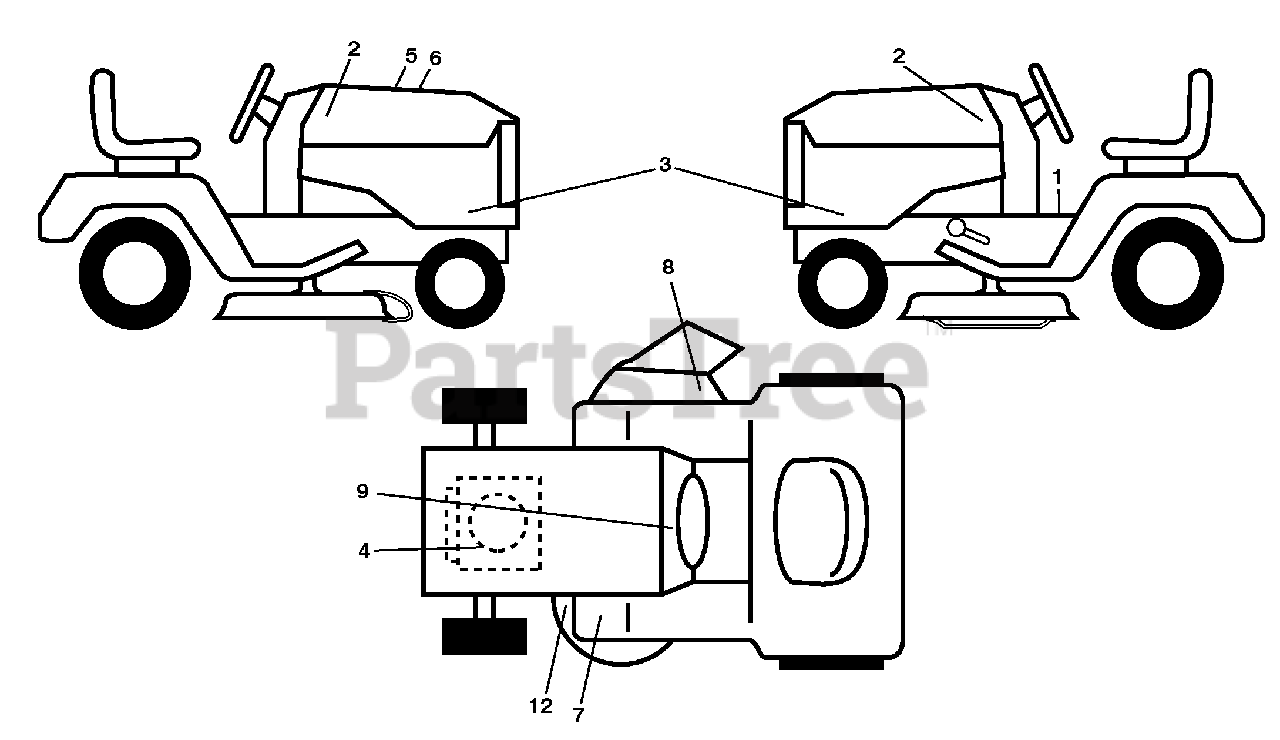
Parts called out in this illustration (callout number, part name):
1	Decal, Operators
2	Decal, Badge
3	Decal, Panel Sd
4	Decal, Eng. Hp
5	Decal, Customer Respons.
6	Decal, Replacement
7	Decal, Pedal Husq. Crown
8	Decal Mower Warn Keep Hand Away
9	Decal, Battery Dnge/Poi
12	Decal, Mower V-Belt Schematic
